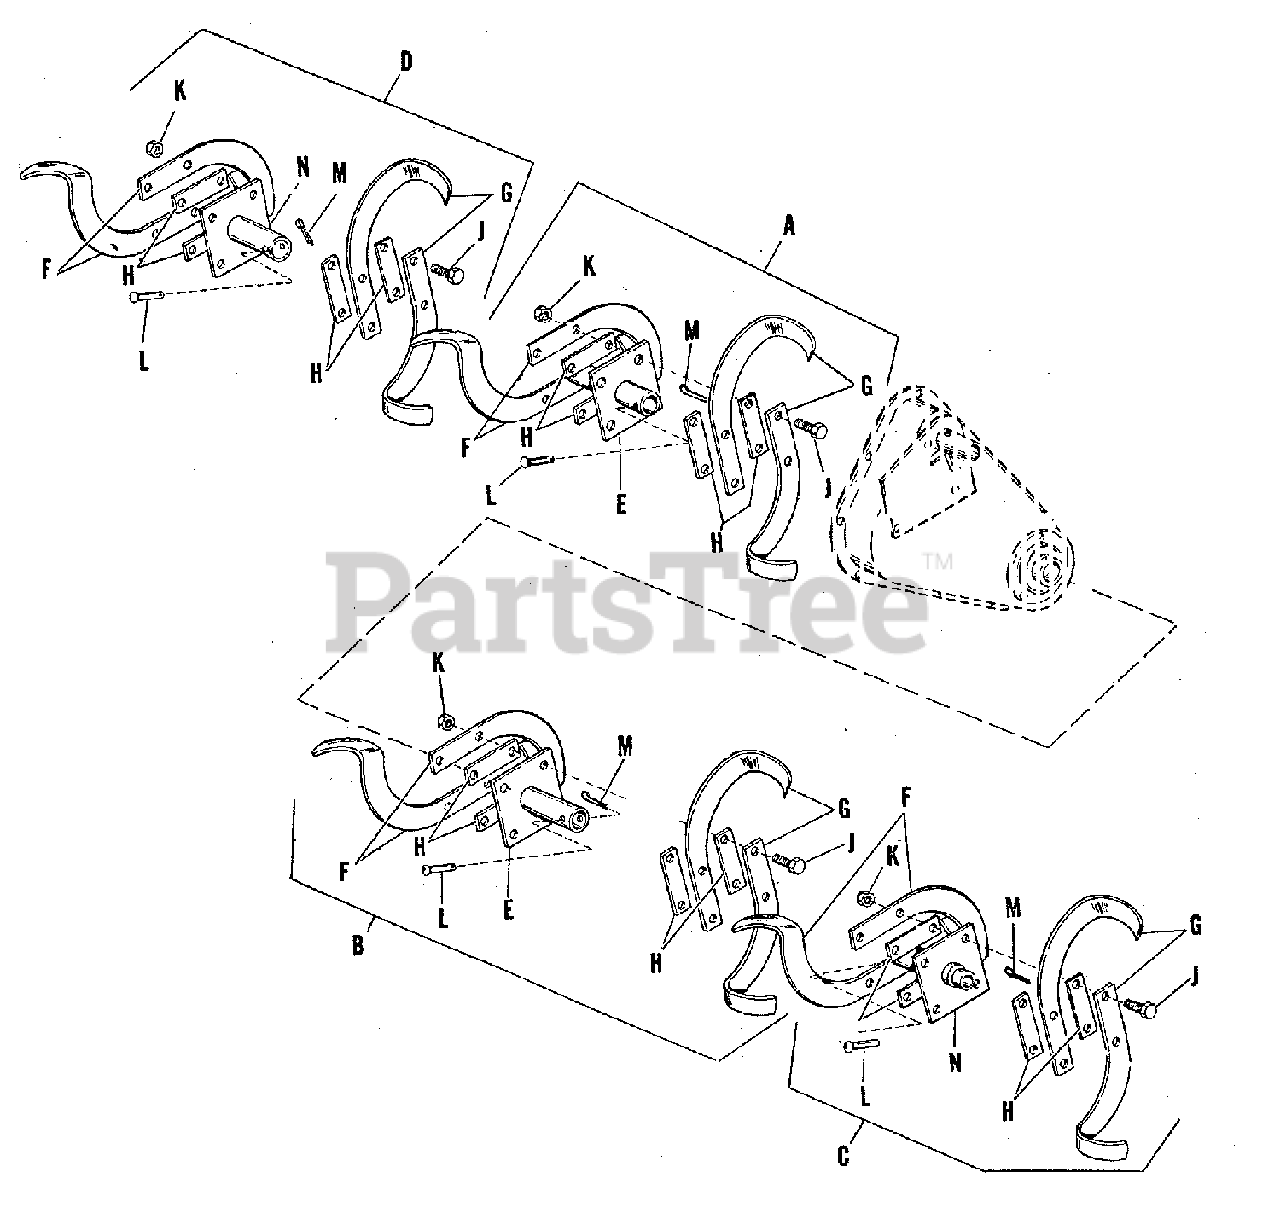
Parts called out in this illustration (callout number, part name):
A	BLADE ASSEMBLY, R.H. Inner Tine
B	BLADE ASSEMBLY, L.H. Inner Tine
C	BLADE ASSEMBLY, R.H. Outer Tine
D	BLADE ASSEMBLY, L.H. Outer Tine
E	PLATE ASSEMBLY, Tine, Inner
F	BLADE, Tine, R.H.
G	BLADE, Tine, L.H.
J	CAPSCREW, Hex, 7/16"-20 NC x 1-3/4" Lg.
K	NUT, Lock, Hex, Full, 7/16"-20 NC
L	PIN, Tine Shaft
M	PIN, Cotter, 1/8" Diameter
N	PLATE ASSEMBLY, Tine, Outer
